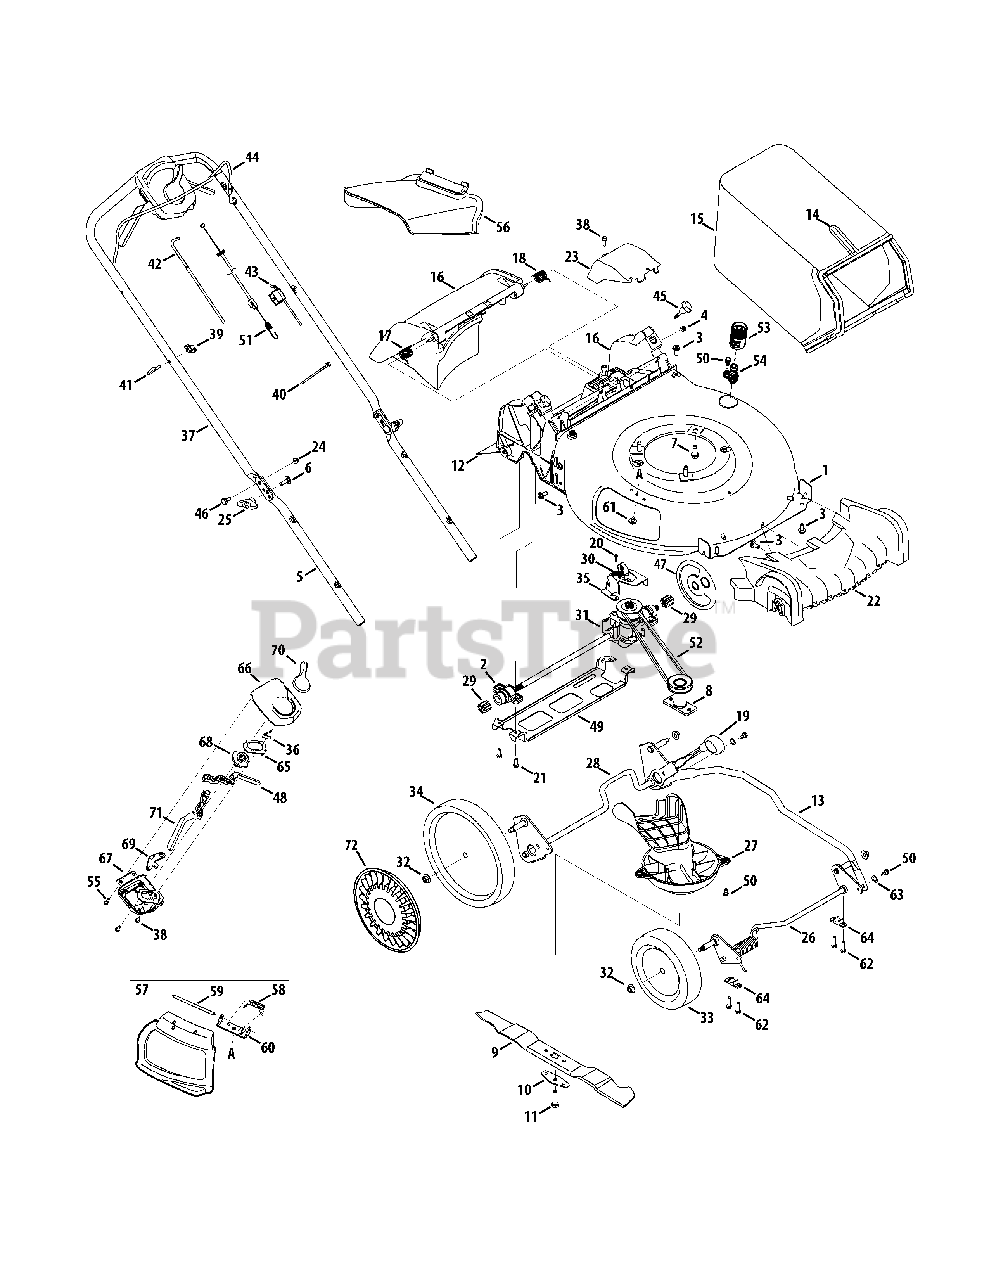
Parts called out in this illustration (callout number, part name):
1	Deck , 21"
2	Bearing Assembly
3	Screw, 5/16-14 x .750
4	Nut, Sq., 1/4-20
5	Lower Handle
6	Carriage Screw ,5/16-18
7	Screw, 3/8-16 x 1.00
8	Blade Adapter
9	Mulching Blade
10	Blade Bell Support
11	Screw, 3/8-24 x 1.50
12	Trailing Shield
13	Cross Bracket
14	Grass Catcher Frame
15	Grass Bag
16	Rear Discharge Door Assembly
17	Torsion Spring - RH
18	Torsion Spring - LH
19	Adjustment Lever Knob
20	Screw, Hex Washer, .159 x .43
21	Screw, 1/4-15 x 1.25
22	Front Cover
23	Transmission Cover
24	Nut, Flange Lock, 1/4-20
26	Front Axle Assembly
27	Engine Baffle
28	Rear Axle Assembly
29	Spur Gear, 9T
30	Exten. Spring, 2.405
31	Transmission Assembly
32	Flange Lock Nut, 3/8-16
33	Front Wheel
34	Rear Wheel
35	Transmission Bracket
37	Upper Handle
38	Screw, 1/4-15 x .750
40	Cable Tie
41	Rope Guide
42	Drive Cable
43	Control Cable
44	Blade Control
45	Wing Nut
46	Sldr. Screw, .375 x .126 x 1/4-20
47	Wheel Dust Cover
48	Control Lever LH
49	Rear Support Bracket
50	Screw, Shldr., 1/4-20 x .50
51	Speed Adjustment Cable
53	Water Nozzle Adapter
54	Water Nozzle
55	Scr., Shldr, 1/4-15 x .970
56	Side Discharge Chute
57	Mulch Plug (Incl. 58-60)
58	Torsion Spring
60	Chute Deflector Bracket
61	Screw, 1/4-20 x .500
62	Screw, 1/4-15 x 1.000
63	Wash., Wave, .385 ID x .598 OD
64	Bushing, Lock, .505 Dia. X .62
65	Cable Adjust Plate
66	Upper Housing
67	Lower Housing
68	Speed Adjust Actuator
69	Drive Cable Actuator
70	Speed Select Lever
71	Control Lever RH
